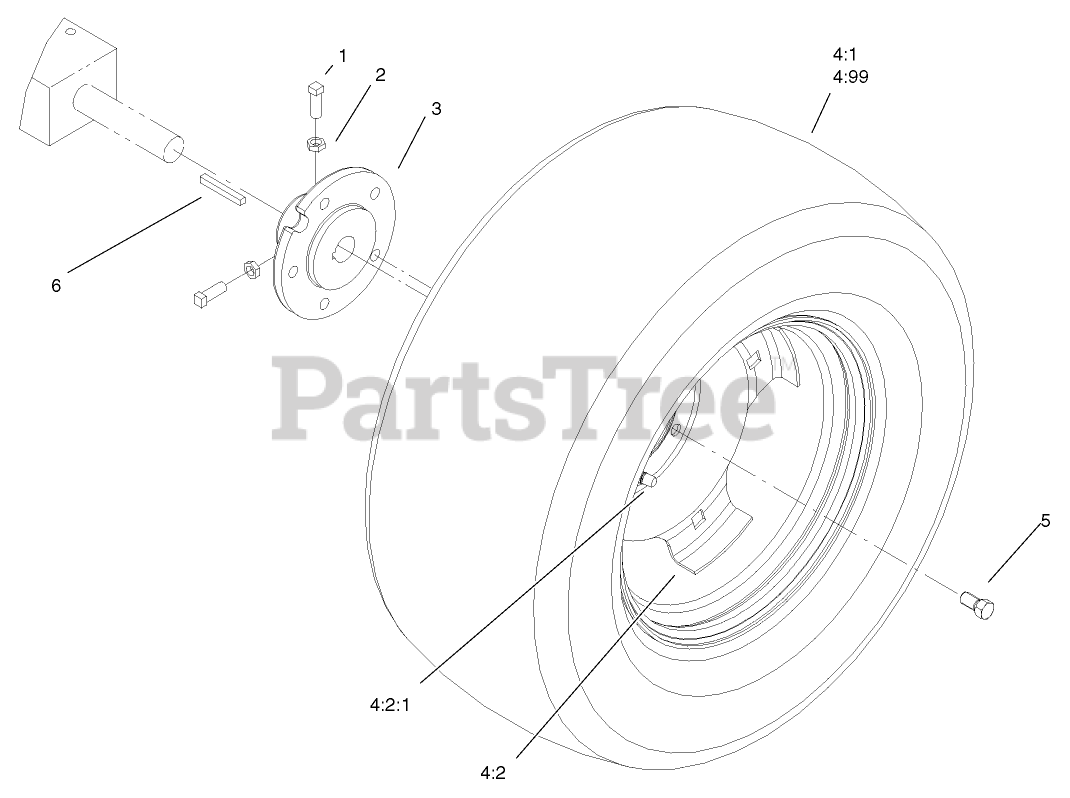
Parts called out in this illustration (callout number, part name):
1	SCREW-SET, SQH
2	NUT-JAM
3	HUB-WHEEL
4	Rear Wheel Tire ASM
4:2	WHEEL
4:2:1	VALVE
5	BOLT-LUG
6	KEY-SQUARE
